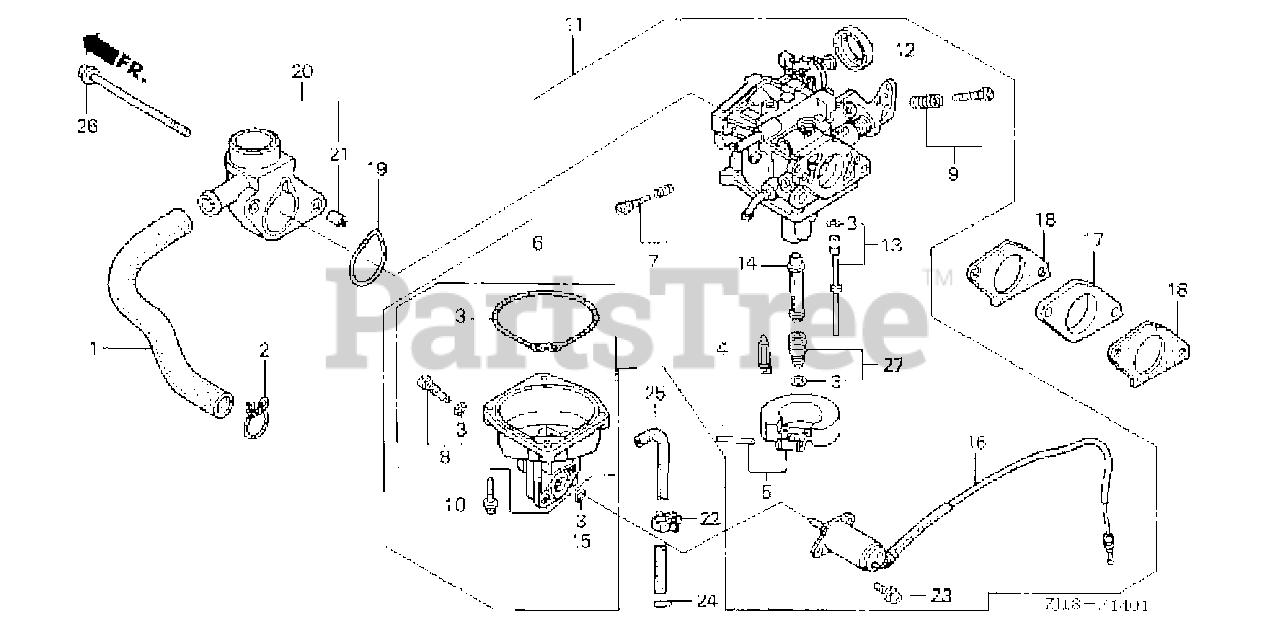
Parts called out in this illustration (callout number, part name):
1	TUBE, BREATHER
2	CLIP, BREATHER TUBE
3	GASKET SET
4	VALVE SET, FLOAT
5	FLOAT SET
6	CHAMBER SET, FLOAT
7	SCREW SET
8	SCREW SET, DRAIN
9	SCREW SET
10	SCREW-WASHER
11	CARBURETOR ASSY. (SPEC)
12	CAP, CHOKE LEVER DUST
13	JET SET (#55)
14	NOZZLE, MAIN
15	O-RING (5.8X1.9)
16	VALVE ASSY., SOLENOID
17	INSULATOR, CARBURETOR
18	GASKET, CARBURETOR
19	GASKET, AIR CLEANER
20	ELBOW, AIR CLEANER
21	COLLAR, DISTANCE
22	CLIP B, CABLE
23	SCREW-WASHER (5X12)
24	CLIP, TUBE (B8)
25	BULK HOSE, VACUUM (4.5X1000) (4.5X460)
26	BOLT, FLANGE (6X105)
27	JET SET, MAIN (#90)
27	JET SET, MAIN (#92)
27	JET SET, MAIN (#95)
